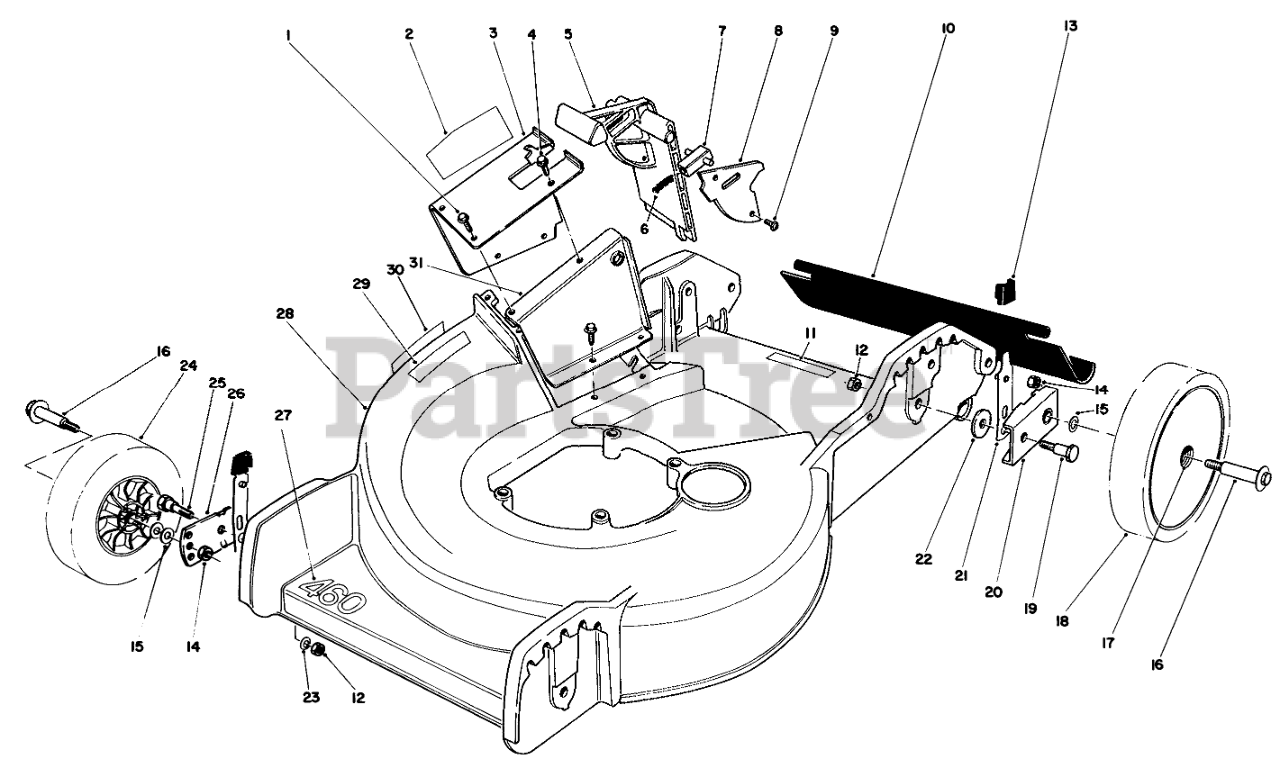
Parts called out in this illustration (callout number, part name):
1	SCREW
2	Decal-Danger
3	Tunnel-Outer (Incl. Ref. #2)
4	SCREW
5	Door Mulching
6	SPRING-COMPRESSION, LATCH
7	Door Latch
8	Cover Door
10	SHIELD - TRAILING
11	Decal
12	NUT-LOCK, NI
13	KNOB-ARM
14	Nut
15	WASHER
16	BOLT-WHEEL
17	BUSHING
18	Wheel & Tire Assembly (Incl. Ref. #16)
19	PIVOT SCREW
20	PIVOT ARM ASM
21	SPRING ARM ASM
22	PIVOT WASHER
23	WASHER-BELLEVILLE
24	Wheel & Tire Assembly (Incl. Ref. #16)
25	5/16-18 PIVOT SCREW
26	PIVOT ARM ASSY
27	Decal-460
28	Housing
29	Decal-Place Foot Here
30	STEP PAD DECAL
31	Tunnel-Inner
